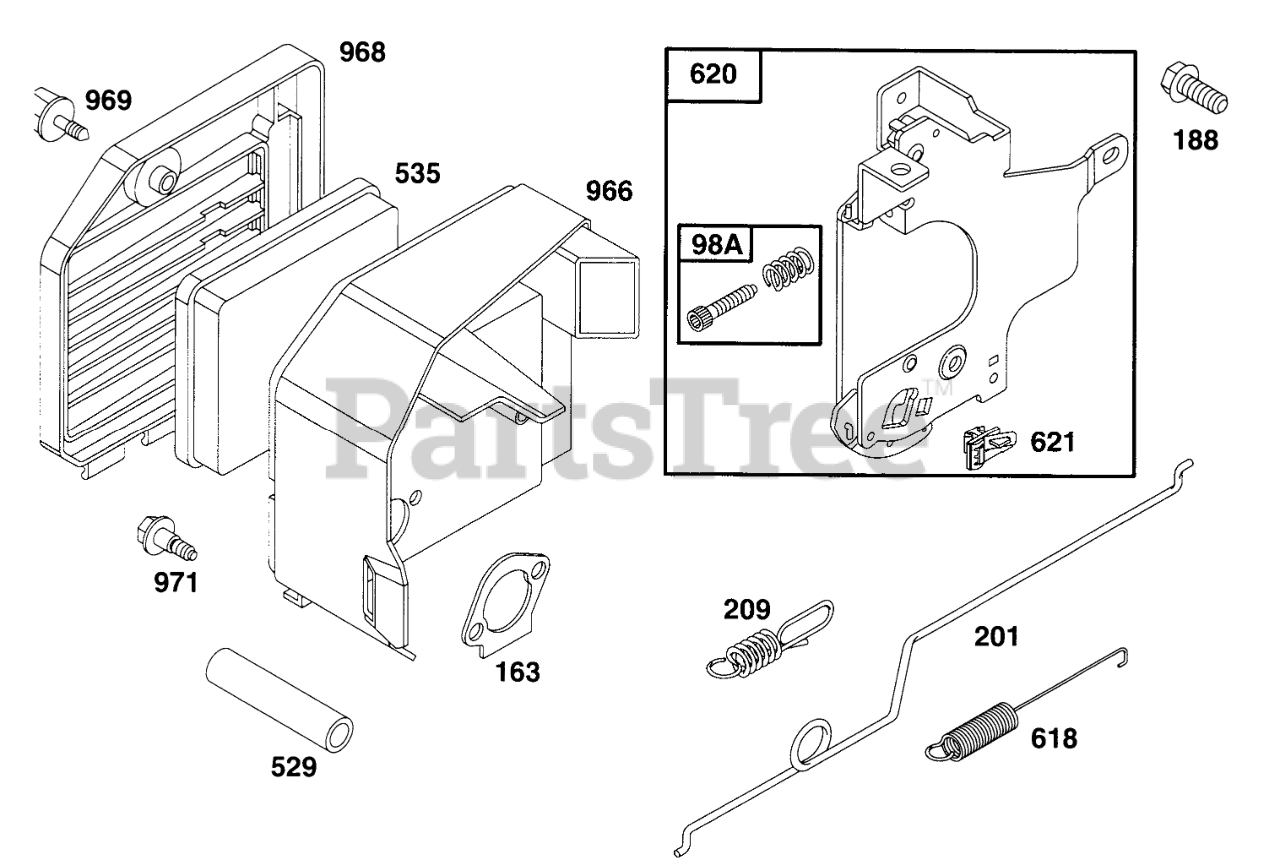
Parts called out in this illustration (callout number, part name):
98A	SPEED ADJUST. SCREW ASM
163	AIR CLEANER GASKET
188	Screw-Cap
201	GOVERNOR LINK
209	GOVERNOR SPRING
529	TUBE - BREATHER
535	FILTER ELEMENT
618	RETURN SPRING
620	CARBURETOR BRACKET
621	STOP SWITCH
966	AIR CLEANER BASE
968	AIR CLEANER COVER
969	AIR CLEANER SCREW
971	AIR CLEANER SCREW
